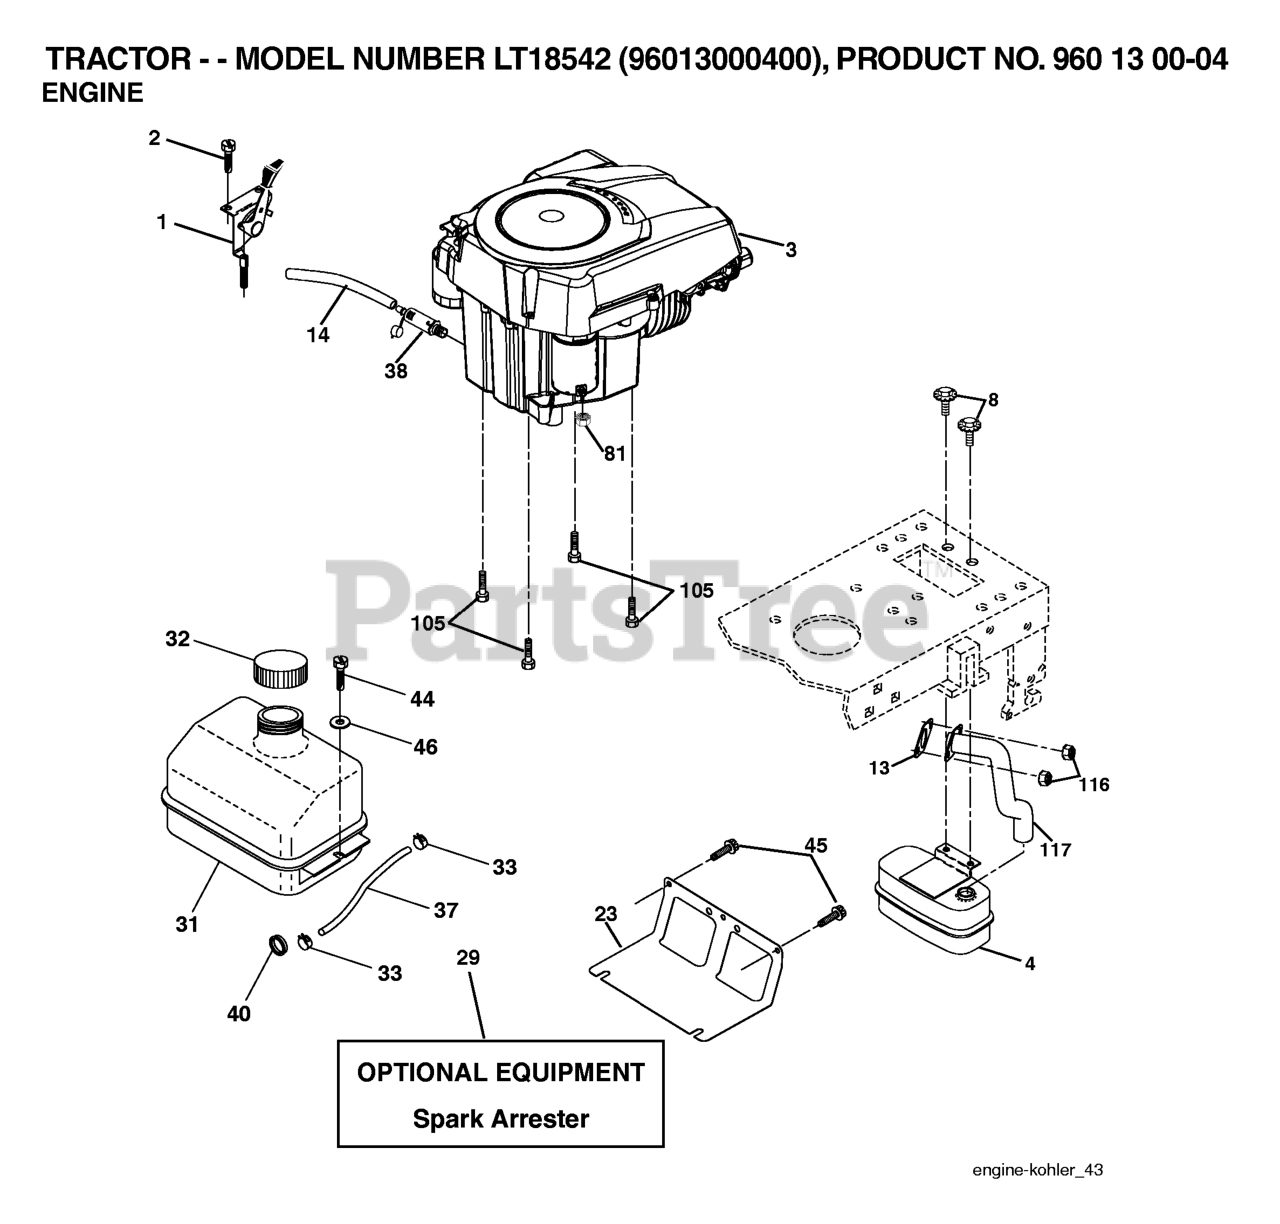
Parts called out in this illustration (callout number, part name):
1	CONTROL.THROTTLE.LT/YT
2	SCREW
4	MUFFLER.SINGLE.CYL.KOHL/B&S
8	BOLT.5/16-18UNCX3/4 W/SEMS.BLK
14	TUBE, DRAIN OIL ASM.
23	SHIELD.BROWNING.DBR.GUARD
29	KIT.SPARK ARRESTOR 794945 B&S
31	TANK.ASM.FUEL.FRONT.W/CAP
32	FUEL CAP
33	HOSE CLAMP
37	LINE.FUEL.20
38	PLUG DRAIN OIL EASY
40	BUSHING.SNAP.NYL.BLK.
44	SCREW HEXWSHR 1/4-20X3/4
45	SCREW, 3/8-16X3/4
81	NUT
105	SCREW 3/8-16X1
116	NUT.HEX.FLANGE.TOPLOCK
117	RP.TUBE.EXHAUST.KOHL.COURAGE
